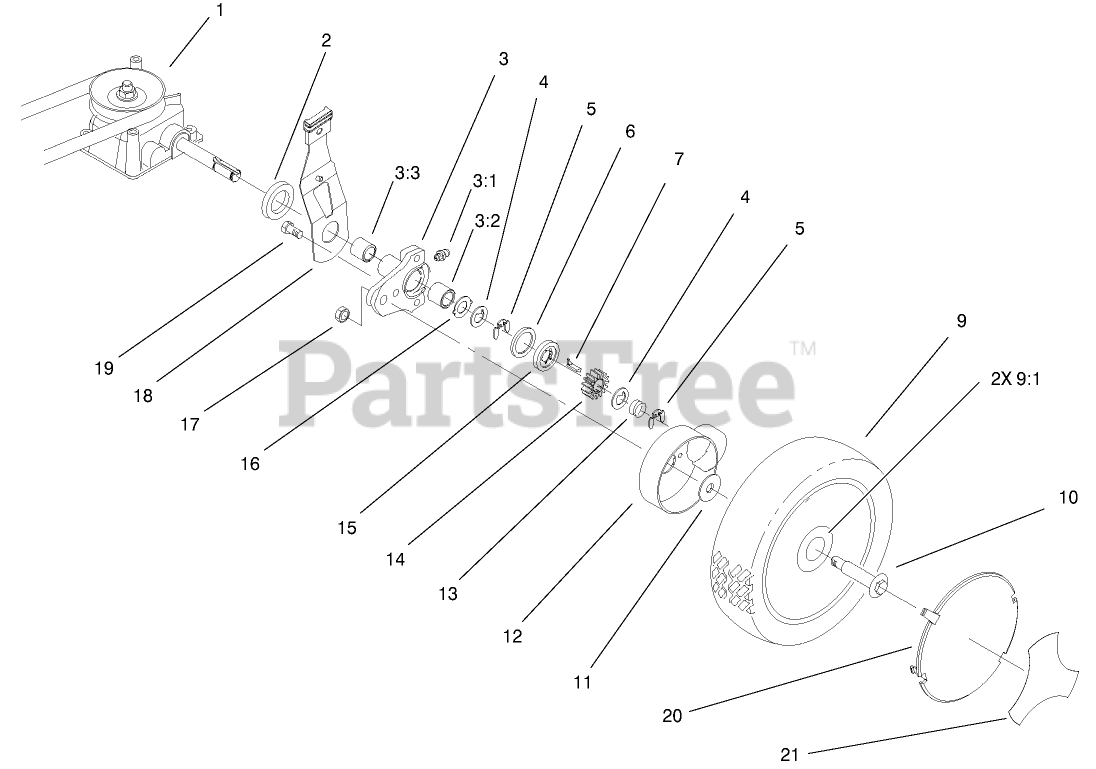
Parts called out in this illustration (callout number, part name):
1	V-BELT
2	SPACER-SHAFT, AXLE
3	REAR HEIGHT ADJUSTMENT ARM ASM
3:1	FITTING-GREASE
3:2	BUSHING
3:3	BUSHING
4	WASHER-THRUST, KEYED
5	RING-RETAINING,CLIP
6	RING-FRICTION
7	KEY-ROCKING, RH
9	WHEEL ASM
9:1	BUSHING
10	BOLT-SHOULDER
11	WASHER-STEPPED
12	COVER-WHEEL
13	SPRING-COMPRESSION
14	GEAR-PINION
15	WASHER-CLUTCH
16	WASHER-ARM, PIVOT
17	LOCKNUT
18	REAR SPRING ARM ASM
19	SCREW-HWH
20	COVER-WHEEL, SMART
21	LABEL-WHEEL, SMART
